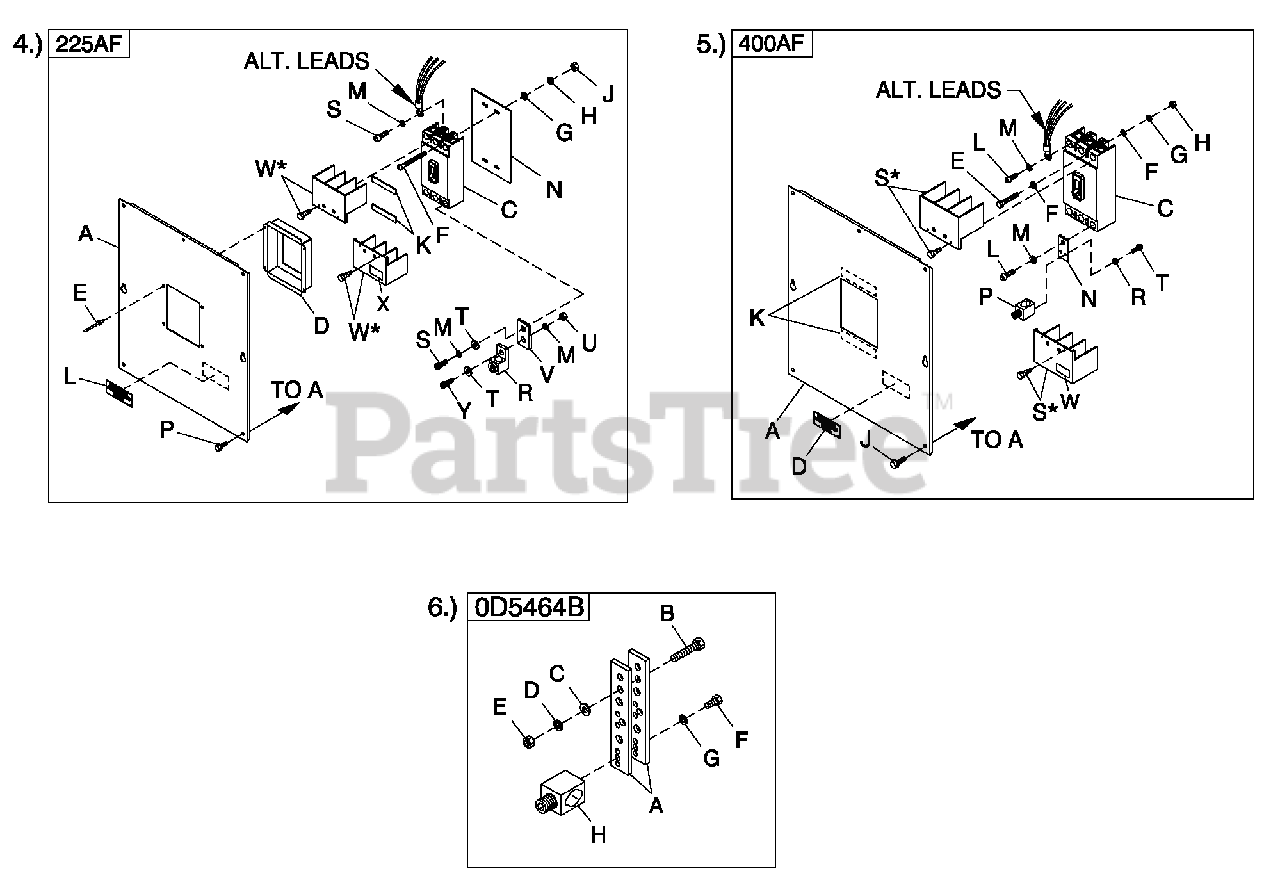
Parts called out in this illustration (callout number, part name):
A	COVER CB C3 225AF
C	CIRCUIT BREAKERS 200A FRAME
D	COVER CB DISH 225AF
E	RIVET POP .125 X .275 SS
F	SCREW RHM #8-32X3-1/4
G	WASHER FLAT #8 ZINC
H	WASHER LOCK #8-M4
J	NUT HEX #8-32 STEEL
K	TAPE ELEC 1/2 FOAM
L	DECAL CUSTOMER CONNECT INSIDE
M	WASHER LOCK M8-5/16
N	INSULATOR CB 225AF
P	SCREW THF M6-1 X 16 N WA Z/JS
R	LUG SLDLSS 300 MCM-6 AL/CU
S	SCREW SHCM8-1.25X 20 G8
T	WASHER FLAT 5/16-M8 ZINC
U	NUT HEXM8-1.25G8 CLEAR ZINC
V	BUS BAR 200A LUG ADAPTOR
W	TERMINAL COVER CB
X	DECAL TERMINAL SHOCK HZD BI
Y	SCREW SHC M8-1.25 X 25 G12.9
A	COVER CB C3 400AF
C	CIRCUIT BREAKERS 400A FRAME
D	DECAL CUSTOMER CONNECT INSIDE
E	SCREW RHM 10-32X4
F	WASHER FLAT #10 ZINC
G	WASHER LOCK #10
H	NUT HEX #10-32 STEEL
J	SCREW THF M6-1 X 16 N WA Z/JS
L	SCREW SHC M10-1.5 X 25 G12.9
M	WASHER LOCK M10
N	BUS BAR CB ADAPTER 225-400 A
P	LUG SLDLSS 600/250-1/0 X 1/4-28
R	WASHER FLAT 3/8-M10 ZINC
S	TERM COVER CB
T	SCREW HHC 1/4-28 X 1/2 G5
U	SCREW SHC M10-1.5 X 25 G12.9
V	WASHER LOCK M10
W	DECAL TERMINAL SHOCK HZD BI
A	BUS BAR NEUTRAL BLOCK 390
B	SCREW HHC M8-1.25 X 45 G8.8 FT
C	WASHER FLAT 5/16-M8 ZINC
D	WASHER LOCK M8-5/16
E	NUT HEXM8-1.25G8YEL CHR
F	SCREW HHC 1/4-28 X 3/4 G5
G	WASHER LOCK M6-1/4
H	LUG SLDLSS 600/250-1/0X1/4-28
